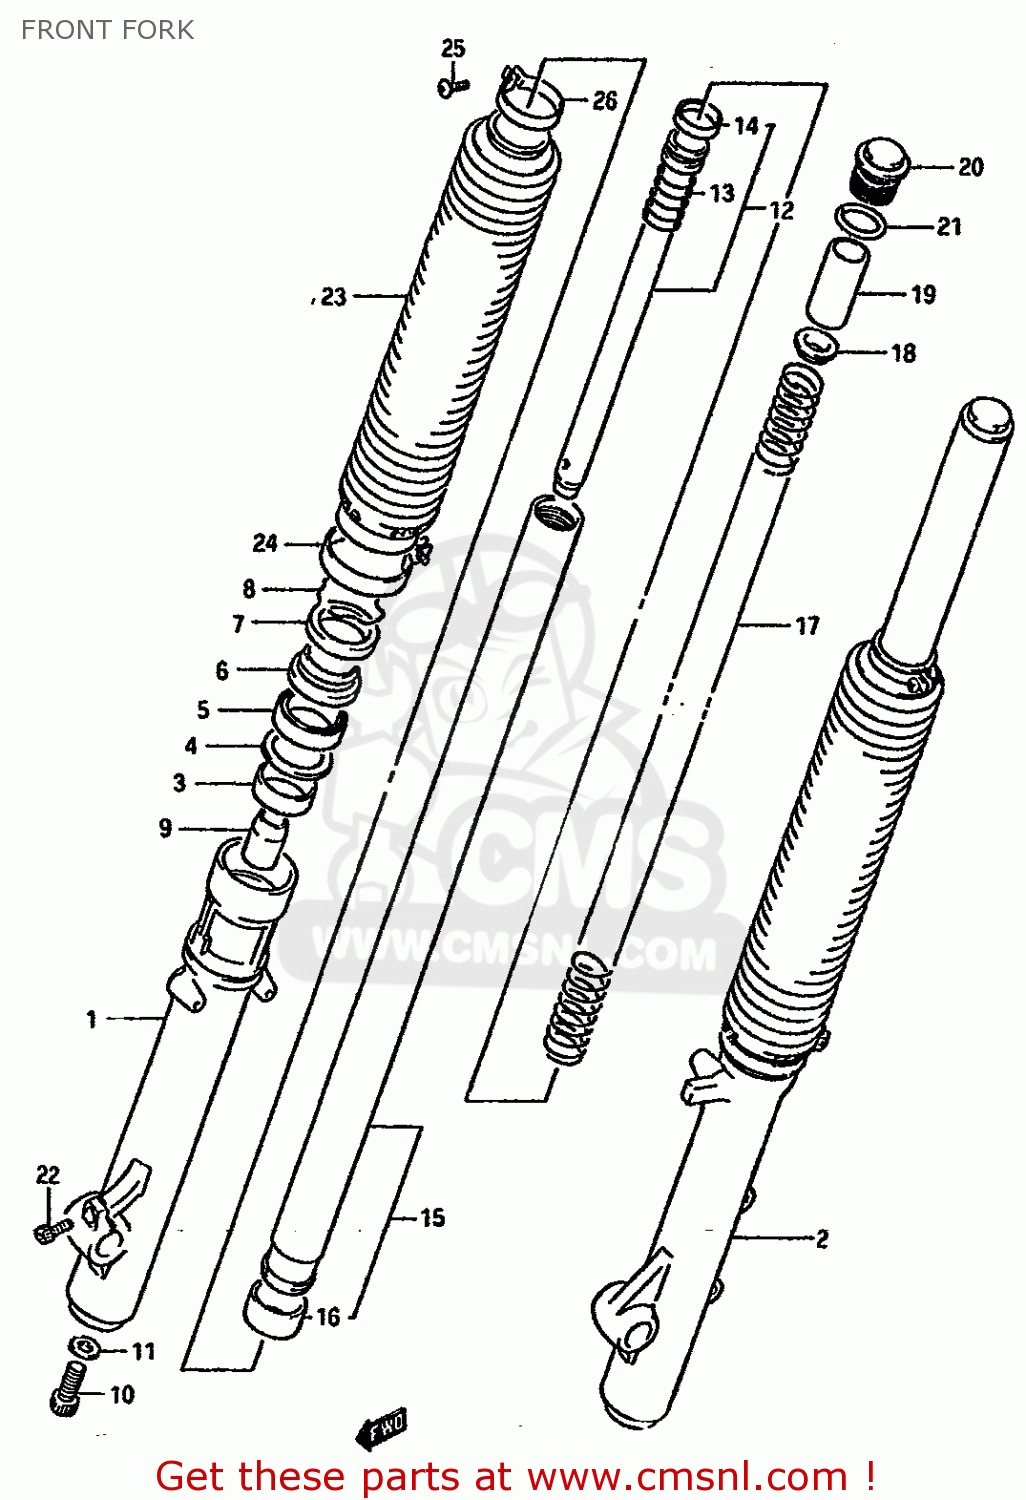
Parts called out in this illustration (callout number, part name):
1	TUBE,OUTER RH
2	TUBE,OUTER LH
3	METAL,SLIDE
4	WASHER,FORK OIL SEAL
5	SEAL,OIL
6	SEAL,DUST
7	WASHER
8	RING,OIL SEAL STOPPER
9	PIECE,FRONT FORK OIL LOCK
10	BOLT,CYLINDER
11	GASKET,CYLINDER (NAS)
12	CYLINDER
13	SPRING
14	RING,FRONT FORK PISTON
15	TUBE,INNER
16	PISTON
17	SPRING
18	GUIDE,SPRING
19	SPACER
20	BOLT,FORK
21	O RING
22	BOLT,SOCKET HEAD(8X22)
23	BOOT (BLUE)
24	BAND,BOOT LWR
25	SCREW
26	BAND,BOOT
